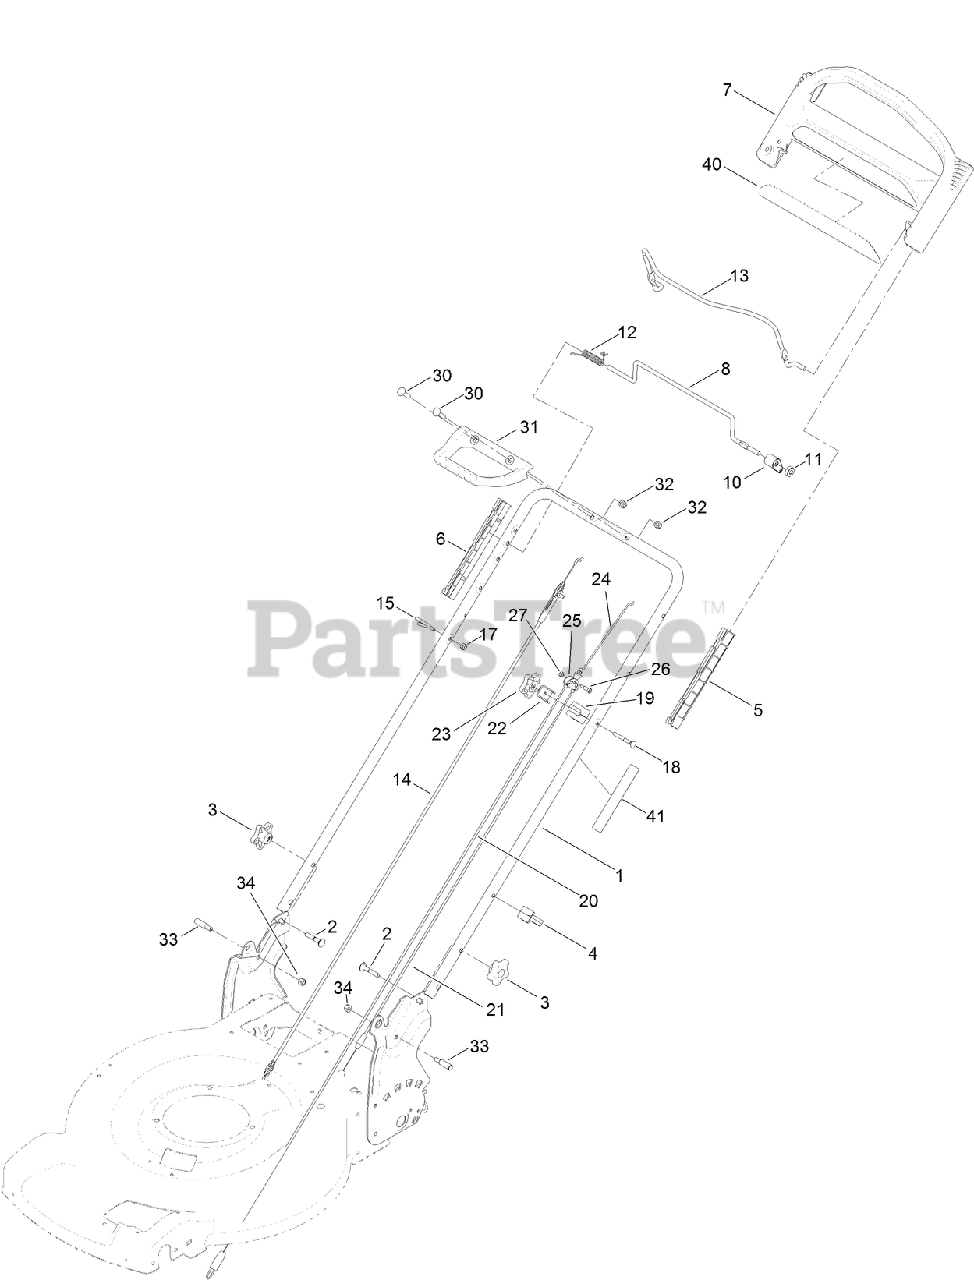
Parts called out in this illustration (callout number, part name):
2	SCREW-CARR
3	KNOB-HANDLE
4	GUIDE-CABLE
5	GUIDE-LH
6	GUIDE-RH
7	HANDLE-CONTROL
10	LEVER-TRACTION
11	SPACER
13	BAIL-BRAKE
14	CABLE-BRAKE
15	GUIDE-ROPE
17	NUT-LOCK, NI
18	SCREW-HANDLE
19	MOUNT-CABLE, TRACTION
20	CABLE-TRACTION, FRONT
21	CABLE-TRACTION, REAR
22	CLAMP-CABLE
23	KNOB-HANDLE, LOCKING
24	LINKAGE-EQUALIZER
25	YOKE-CABLE
26	SCREW-SHOULDER
27	NUT-LOCK, NI
30	BOLT-CARRIAGE
31	HANDLE-ASSIST, TRACTION
32	NUT-ACORN
33	BOLT-SHOULDER
34	NUT-LOCK, NI
40	DECAL-DRIVE, AUTOMATIC
41	DECAL-TRACTION, ADJUST
